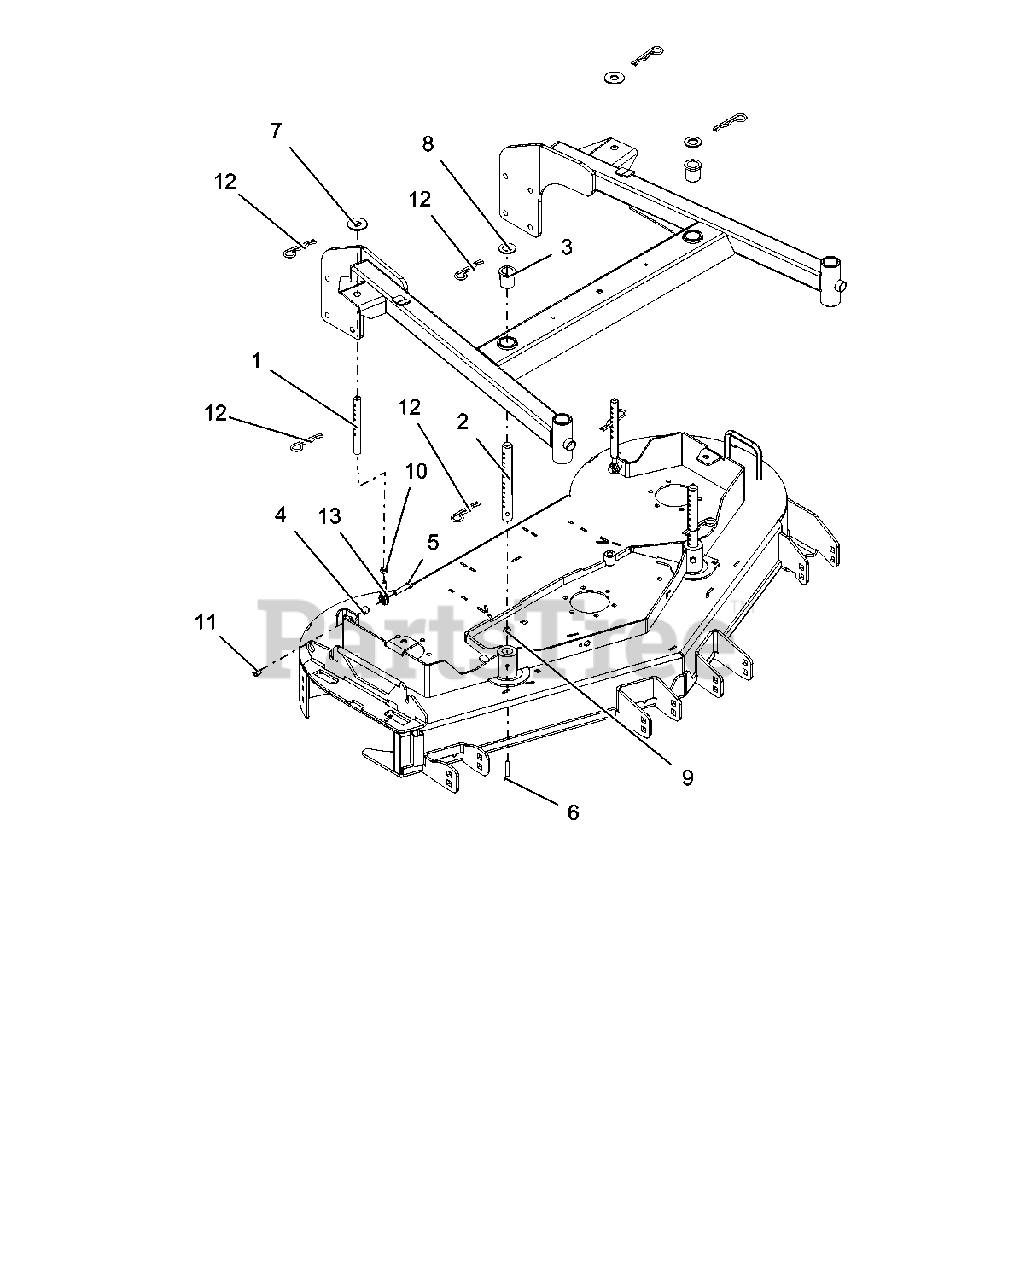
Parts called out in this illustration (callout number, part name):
1	ROD, REAR HOC
2	PIN, FRONT HOC
3	BSHG-FLG 1.00X1.25X1.5X1.5
4	BSHG, SLV REV
5	BLT-HEX .38-16X1.75 GR5 YWZC
6	BLT-HEX .31-18X2.50 GR8 YWZC
7	WSHR-FL-STL.688X1.75X.134 YWZ
8	WSHR-FL-STL .875X1.500X.1196YZ
9	@NUT-SPNLK-FLG .312-18 YWZC
10	NUT-JAM .375-24 YWZC
11	NUT-LK-NYL .38-16 YWZC
12	PIN-HAIR-INT .17X.68X3.50 YWZC
13	ROD, END 3/8 RH REV
